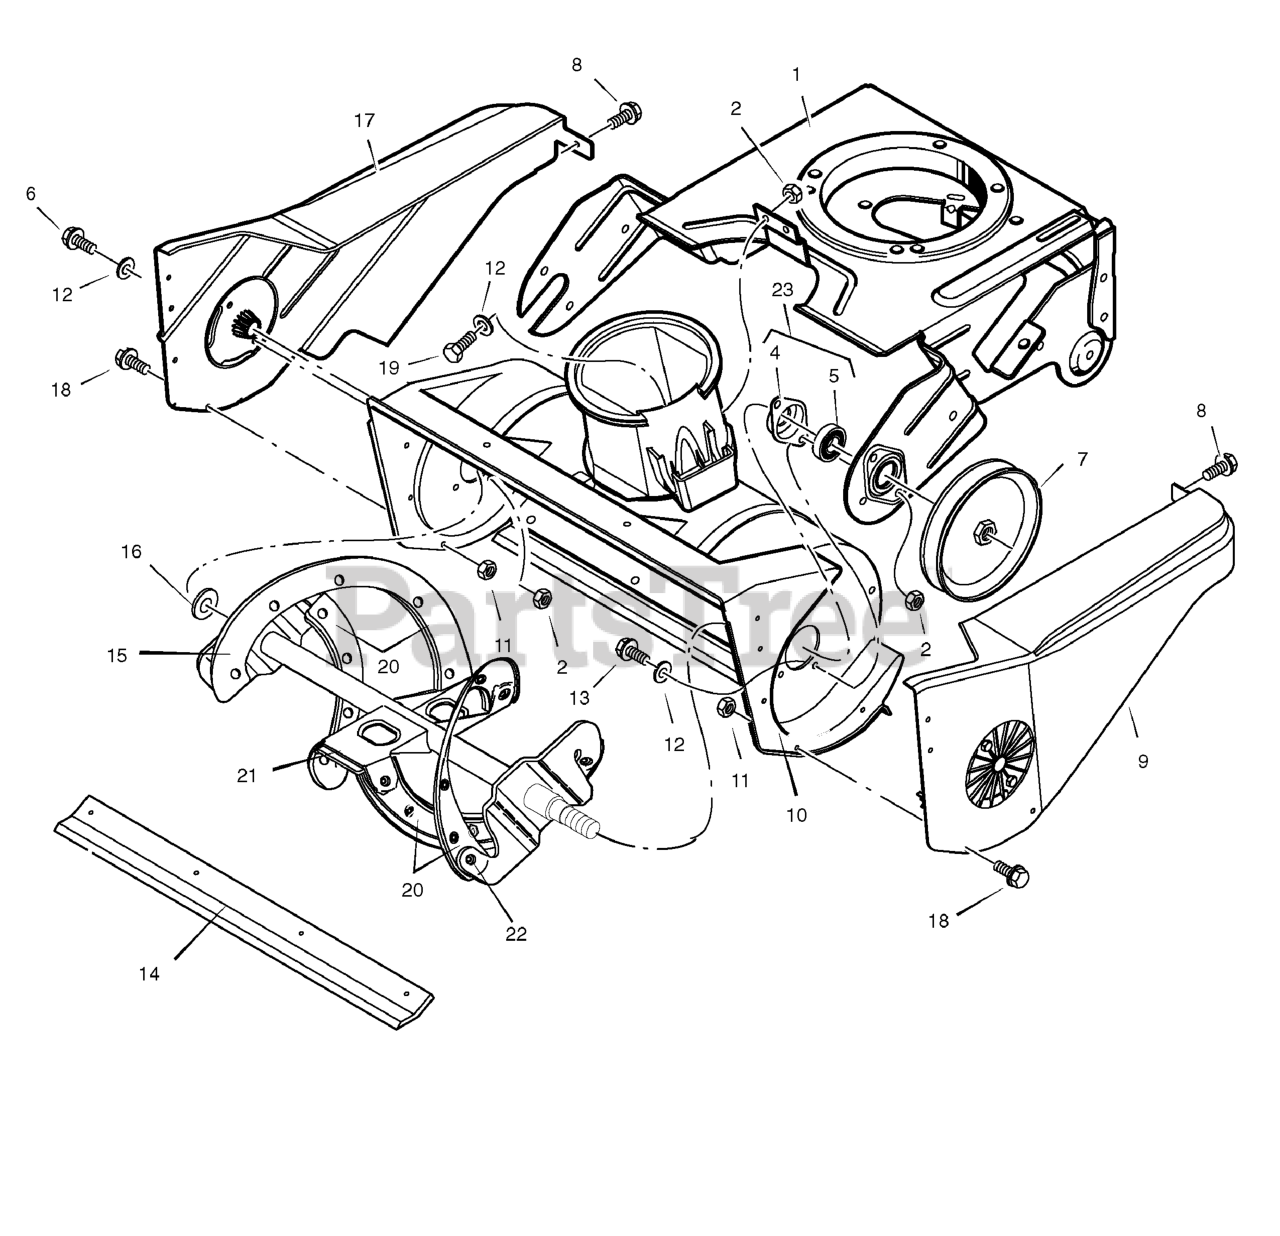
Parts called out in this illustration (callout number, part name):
1	Frame, Motor Box
2	Nut, 1/4-20
4	Retainer, Bearing
5	Bearing, Ball
6	Screw, 1/4-20x.75
7	Pulley, Auger
8	Screw, 1/4-20
9	Cover, Belt 21" Left Hand
10	Assembly, Auger Housing
11	Nut, 10-24
12	Washer, Flat
13	Screw, 1/4-20x.63
14	Blade, Scraper
15	Auger Assembly, Complete
16	Washer, Flat
17	Cover, Belt 21" Right Hand
18	Screw, 10-24x.50
19	Screw, 1/4-20x.75
20	Blade, Auger
21	Blade, Center
23	Plate and Bearing Assembly
